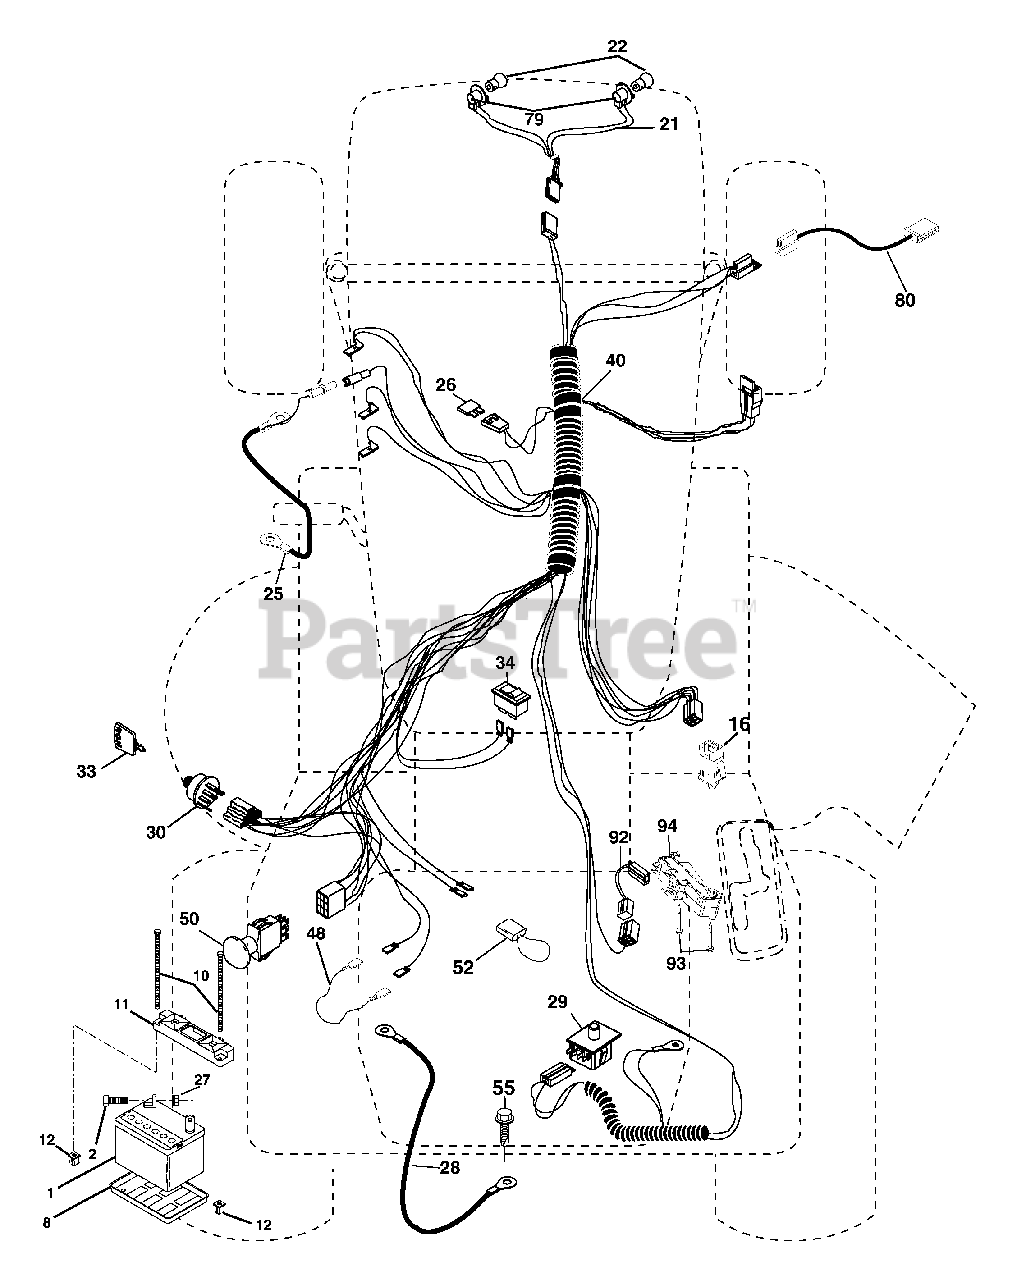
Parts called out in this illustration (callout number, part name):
1	Battery
2	Bolt Hex Hd 1/4-20 unc x 3/4
8	Tray Battery
10	Bolt Battery 1/4-20 x 7.5
11	Holddown Battery
12	Nut Push Nylon 1/4"
16	Switch Interlock
21	Harness Socket Light
22	Bulb, Light # 1156
24	Cable Battery
25	Cable Battery
26	Fuse
27	Nut Keps Hex 1/4-20 unc
28	Cable Ground
29	Switch Seat
30	Switch Ign
33	Key Ign Molded Generic
34	Switch Light/Reset B/B/Red
40	Harness Ign
41	Screw 1/4-20 unc x 1/2
42	Cover Terminal Red
43	Solenoid
48	Adaptor Ameter
50	Switch PTO
52	Protection Loop
55	Screw Thdrol 5/16-18 x 1/2
79	Socket Arm Bulb
80	Harness Clutch
92	Harness Pigtail Reverse Switch
93	Screw Plastic 10-14 x 2.0
94	Module Reverse ROS
